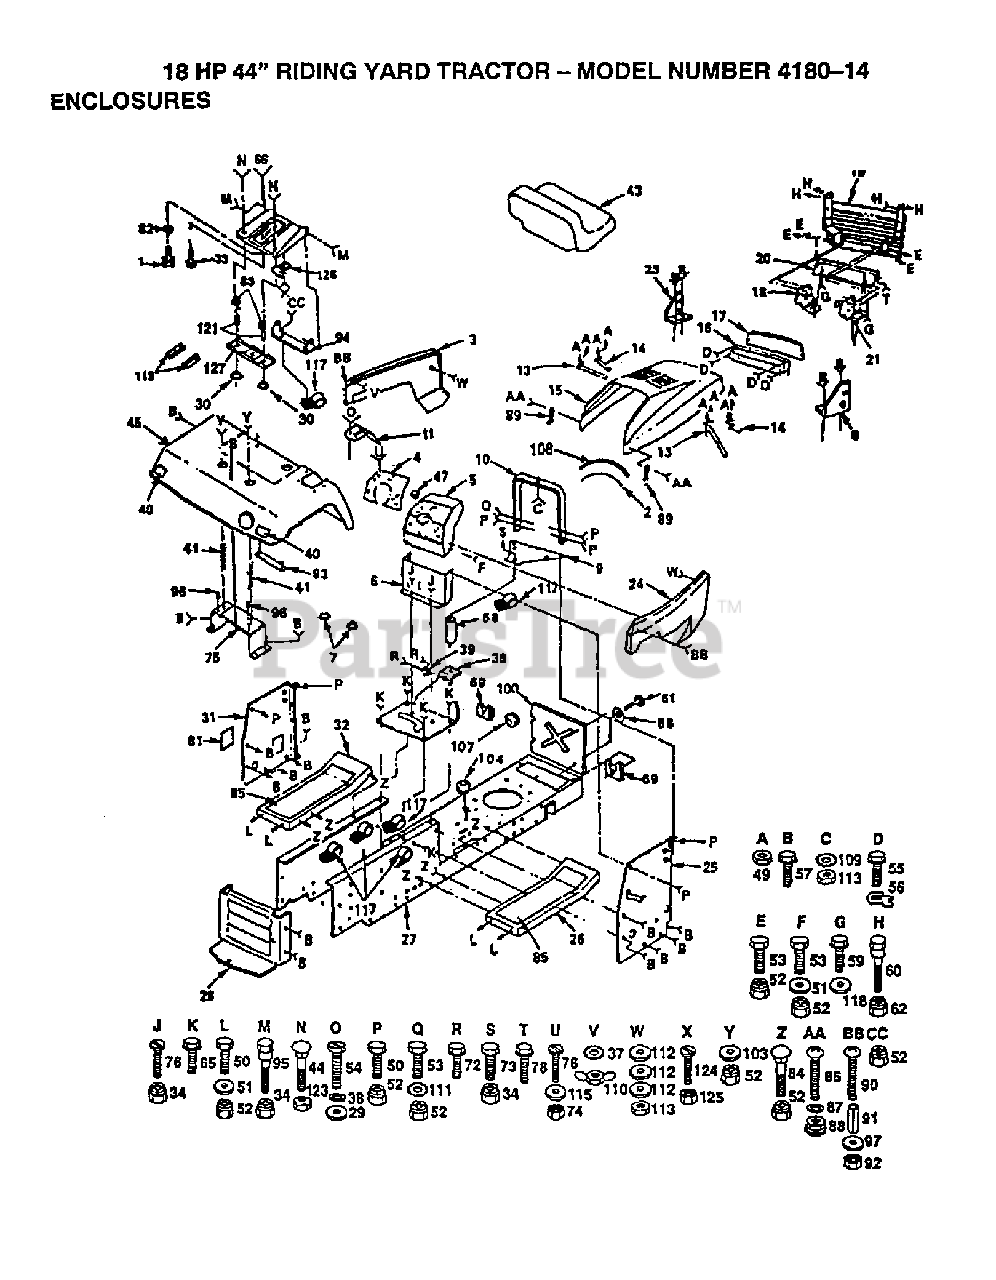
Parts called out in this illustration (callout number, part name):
2	FOAM STRIP T
3	Poulan TBD
4	Poulan TBD
6	DASH LOWER YT NLA
7	CAP SPRING
8	SUPPORT RH YTH
9	PLATE SUPPORT T NLA
11	CONSOLE SHIFTER
15	Poulan TBD
18	SUPPORT LH YTH
20	Poulan TBD
21	BRACKET NLA
23	SUPPORT LH YTH
24	Poulan TBD
25	PANEL LT NLA
26	FOOTREST RH
28	DRAW BAR
31	PANEL DASH LH NLA
32	FOOTREST LH**
33	BOLT, SHOULDER**
34	LOCKNUT
36	BUSHING
37	LOCKWASHER GT
38	Lock Washer
40	REFLECTOR-TAIL YT
41	SPRING COMPRESSION
45	Poulan TBD
47	PLUG BUTTON T
49	NUT
51	WASHER
52	LOCKNUT
53	BOLT
59	Screw, Lt
60	Bolt
61	STUD 1/4 TURN
62	NUT.CROWNLOCK.1/4
63	SPRING COMPRESSED
65	SCREW LT
66	PAN SEAT
68	RETAINER LT
69	RECEPTACLE LT
72	SCREW LT
81	COVER ACCESS
86	SCREW
87	LOCKWASHER
88	NUT.WELD
89	LATCH.HOOD.
90	SCREW
91	SPACER LT
92	NUT **
93	STRAP-FENDER YT
94	BRKT,SEAT PIVOT**
95	BOLT, SHOULDER LT
96	NUT-PUSH YT
97	WASHER
100	SHIELD HEAT HYT
104	SNAP BUSHING T
108	FOAM STRIP T
109	LOCKWASHER
110	WING NUT
111	LOCKWASHER
112	WASHER PM
113	NUT
115	WASHER
117	CLIP T
118	WASHER
119	STRIP FORM
121	SPACER SPLIT
123	NUT T
124	SCREW **
125	NUT,KEPS
126	CLIP T
127	BRKT SWITCH
